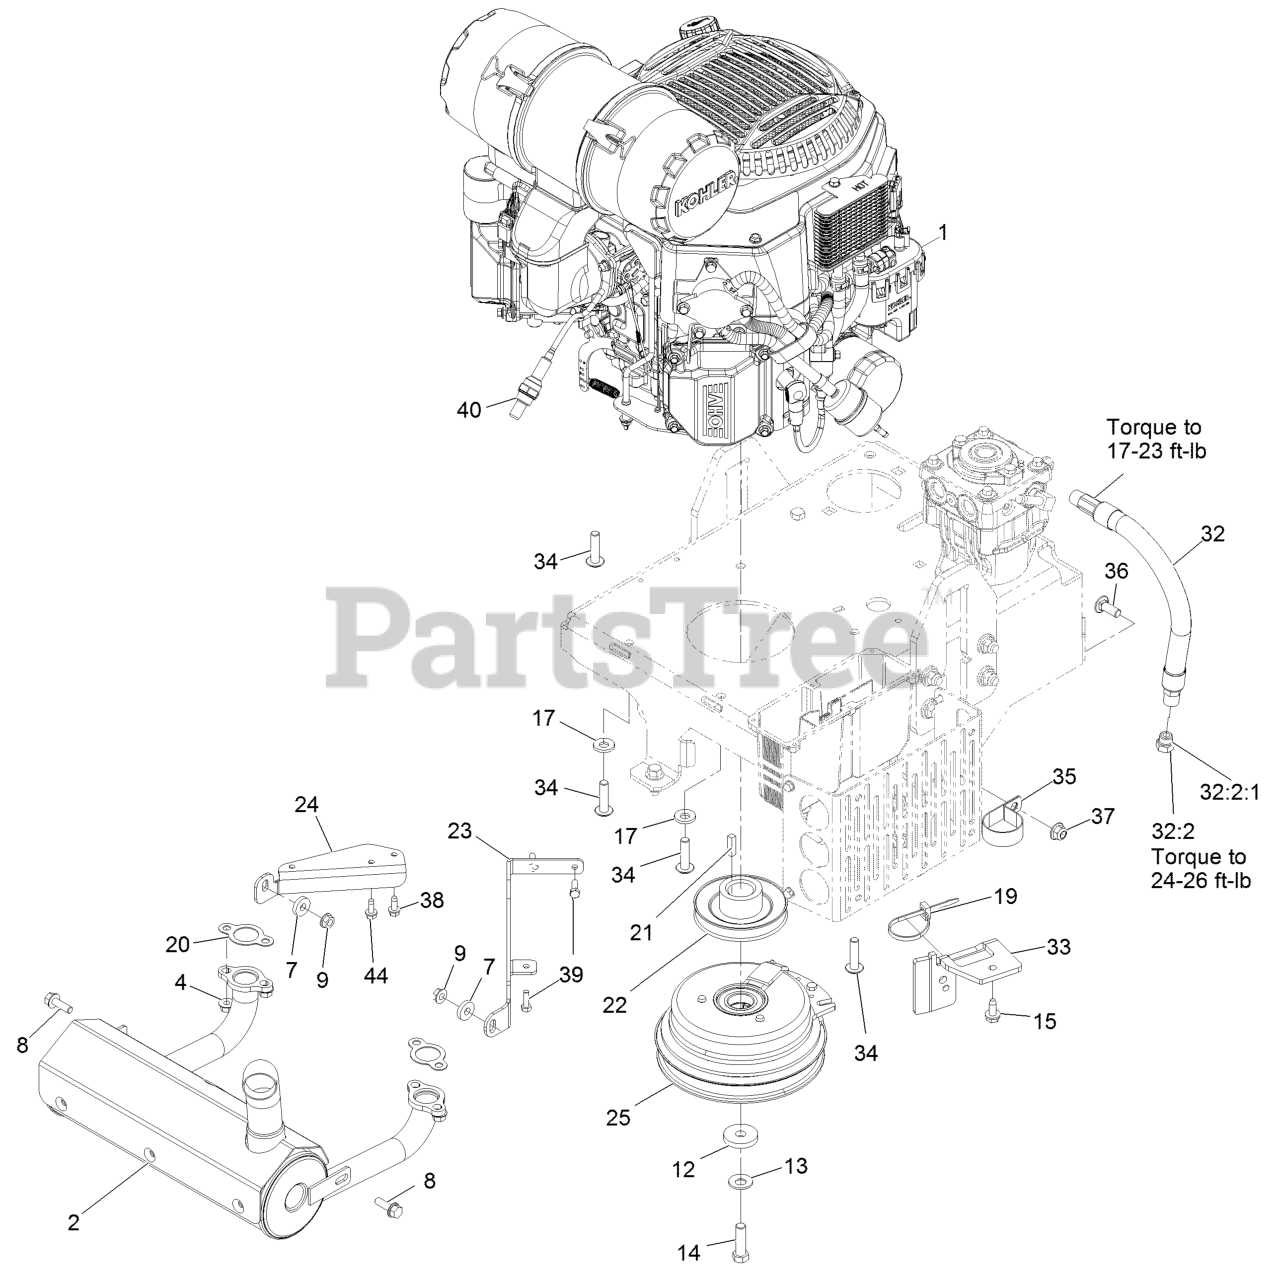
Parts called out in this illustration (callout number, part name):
2	NUT-FLANGE
7	SCREW-HHF
9	WASHER
12	WASHER-SPRING
13	Washer-Spring Disc 7/16
14	Screw-HWH 5/16-18 X 3/4 Tf
15	WASHER-BELLEVILLE
17	TIE-CABLE
19	GASKET-EXHAUST
22	MOUNT, MUFFLER-LT
23	Mount, Muffler-Lt
24	MOUNT, MUFFLER-RT
25	CLUTCH-200 FT-LB, 1.125 B
32	OIL DRAIN HOSE ASM
32:2	PLUG-HH
32:2:1	O-RING
33	BRACKET-ANCHOR, CLUTCH
34	SCREW-BHTF
35	CLAMP-R
36	SCREW-CARR
37	NUT-HF, NI
38	SCREW-HWHTF
39	SCREW-HH M6-1 X 20Mm W/Patch
40	SENSOR-OXYGEN
44	SCREW-HWHTF
